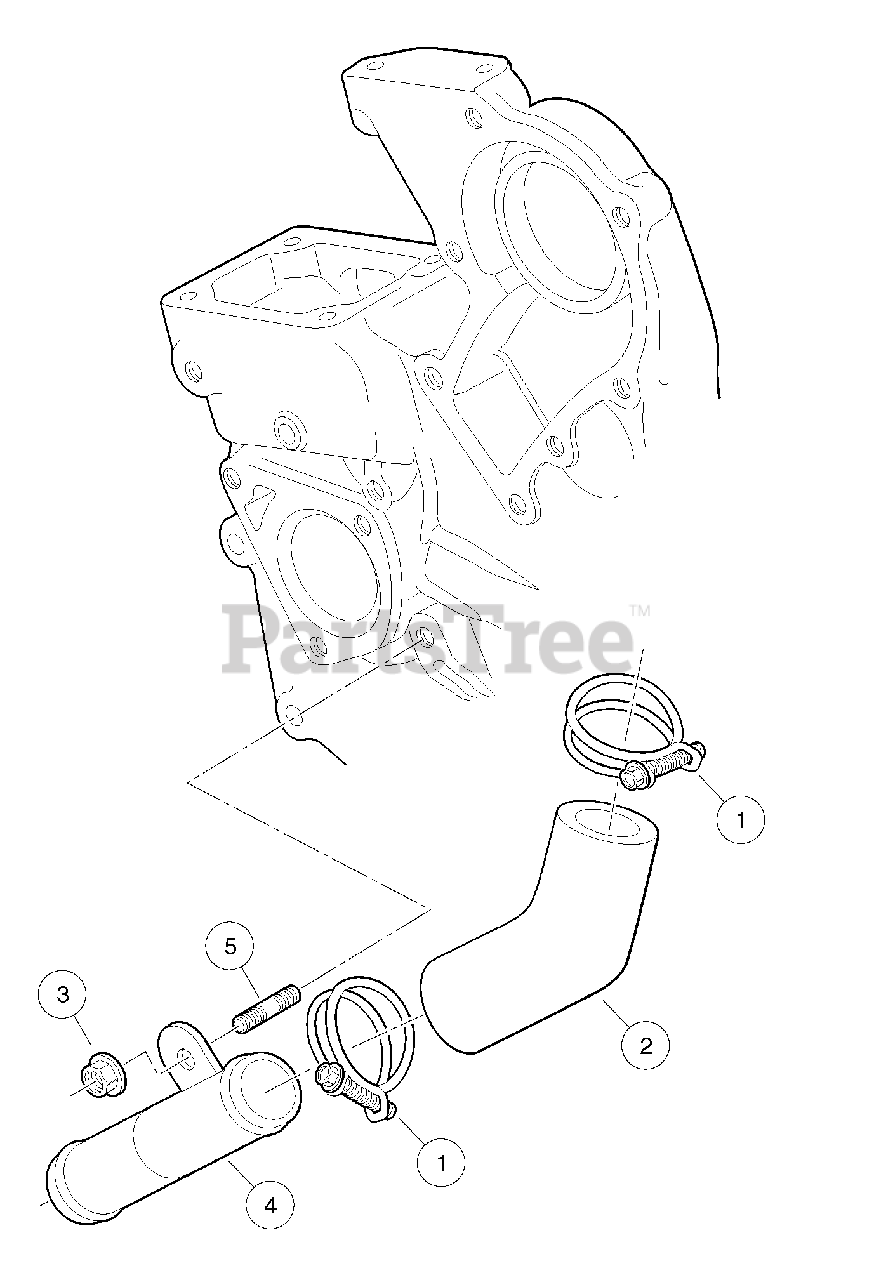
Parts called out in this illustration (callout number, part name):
1	Band, Pipe, with Nut
2	Pipe, Water, Bent
3	Nut, Flange, M6
4	Pipe, Water, Bent
5	Stud, M6 X 15
